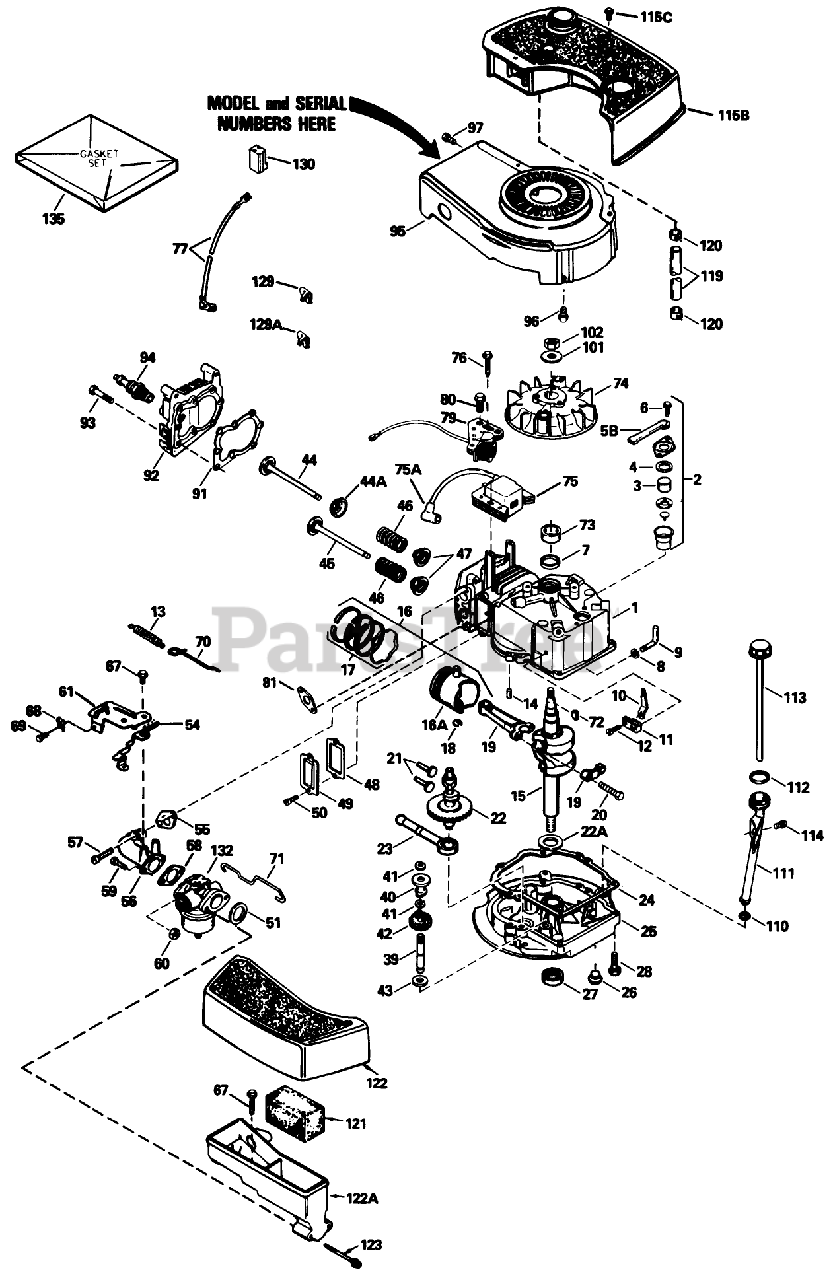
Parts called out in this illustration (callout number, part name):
1	Cylinder Assy. (Inc. #2 4)
2	Breather Assy. (Incl. Ref. #46 thru 51)
3	Element-Breather
4	*33735 Gasket, Breather
5B	Tube, Breaker
6	Screw (10-24 x 9/16)
7	Seal-Oil
8	Washer-Flat
9	Rod, Governor (Incl. No. 36)
10	Governor Lever
11	Clamp-Lever, Governor
12	Screw
13	Spring Governor
14	Pin-Dowel
15	Crankshaft
16	Piston-Pin Ring Assy. (Std.)(Incl. Ref. #16A, 17 18)
16	Piston-Pin Ring Assembly (.010 oversize)(Incl. Ref. #16A, 17 18)
16	Piston, Pin Ring Assy. (.020 Oversize)(Incl. Ref. #13A, 14, 15)
16A	Piston Pin Assy. (Std.)(Incl. Ref. #14)
16A	Piston Pin Assembly (.010 oversize)(Incl. Ref. #18)
16A	Piston Pin Assy. (.020 Oversize) (Incl. Ref. #14)
17	Ring Set-Piston (Std.)
17	Ring Set, Piston(.0100versize)
17	Ring Set (.020" OS)
18	Ring-Retaining, Piston Pin
19	Rod Assy., Connecting (Incl. Ref. #17)
20	Bolt-Rod, Connecting
21	Lifter-Valve
22	Camshaft(Mech.Comp. Release)
22A	Washer-Thrust
23	Oil Pump ASM
24	Gasket
25	Flange-Mounting (Incl. Ref. #26, 27 39)
26	Plug Oil Drain
27	Seal-Oil
28	Screw (1/4-20 x 1-1/4)
39	Shaft-Governor
40	Spool-Governor
41	Ring-Retaining
42	Governor Gear ASM
43	Washer
44	Valve, Intake (Std.) (Incl. Ref. #40)
44	Valve, Intake (1/32" oversize)(Incl. No. 40)
44A	Seal Assy., Intake
45	Valve, Exhaust (Std.)(Incl. No. 40)
45	Valve, Intake (1/32" oversize)(Incl. No. 40)
46	Spring-Valve
47	Cap-Valve, Spring
48	Gasket-Cover, Valve
49	Cover-Valve
50	Screw
51	Gasket-Air Cleaner
54	Lever Control
55	Gasket-Intake Pipe
56	Pipe, Intake (Incl. No. 68)
57	Screw (1/4-20 x 1)
58	Gasket-Carburetor
60	Nut and Lock Washer (1/4-28)
61	Control Assy., Speed (Incl. Nos, 76, 78 89)
67	Screw, Hex Washer Hd Shoulder Self-Tap
68	Conduit
69	Screw (10-32 x 3/8)
70	Link Governor Spring
71	Link-Throttle
72	Key-Flywheel
73	Spacer
74	Flywheel
75	Solid State
75A	Cover-Spark Plug
76	Screw
77	Wire-Ground
79	Coil, Alternator
80	Screw (8-32x27/64)
81	Gasket, Exhaust
91	Gasket-Cylinder Head
92	Head-Cylinder
93	Screw (5/16-18x1-1/2)
94	Spark Plug-Resistor (R J19 L M)
95	Housing-Blower
96	Screw (1/4-20x19/32)
97	Screw (10-24 x 9/16)
101	Washer-Belleville
102	Nut-Flywheel
110	Gasket
111	Tube, Oil Fill
112	O-Ring
113	Dipstick, Oil
114	Screw (10-32 x 1/2)
115B	Tank-Fuel
115C	Screw (10-32 x 35/64)
119	Line-Fuel
120	Clamp-Line, Fuel
121	Filer, Air
122	Cove, Air Cleaner
122A	Body Air Cleaner
123	Screw Fil Hd.
129	Clip-Wire
129A	Clip, Breather
130	Connector-Body
132	Carburetor (Incl. Ref. #71)
135	Gasket Set
